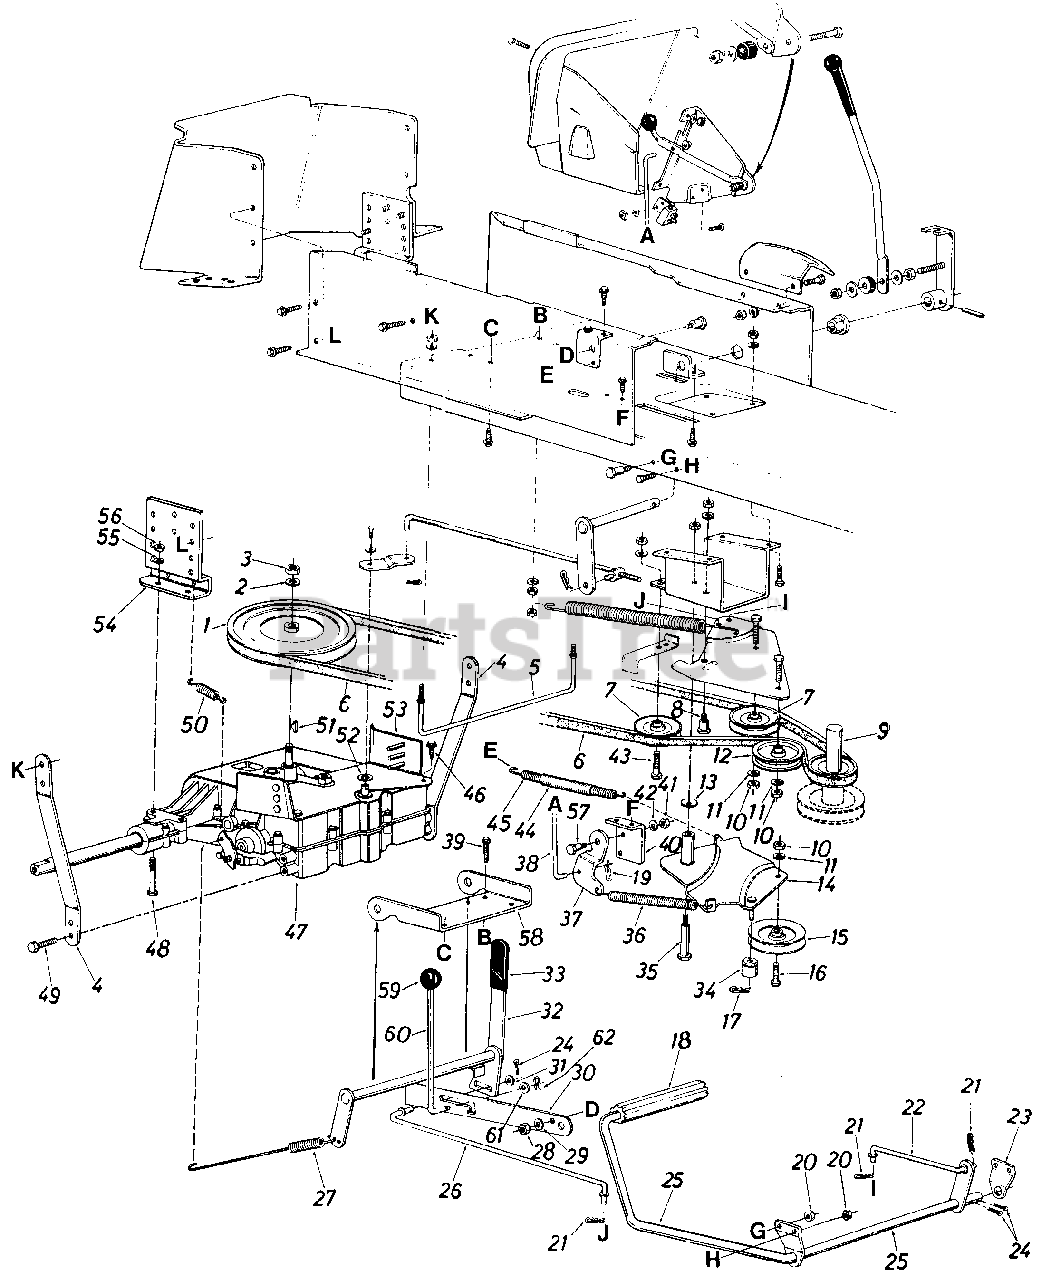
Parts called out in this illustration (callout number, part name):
1	8" "V"-Pulley
2	L-Wash. 1/2" I.D.*
3	Hex Nut 1/2-20 Thd.*
4	Transaxle Brace
6	"V"-Belt
7	"V"-Belt Idler Pulley .38" I.D. x 3-1/16" O.D.
8	Shoulder Bolt .435" Dia. x .160 (5/16-18)
9	Two Step Engine Pulley 3.10" & 5.56" Dia.
10	Hex Nut 3/8-16 Thd.*
11	L-Wash. 318" I.D.*
12	Flat Idler Pulley 2.75" O.D.
13	Belleville Wash. .400'1 I.D. x .88" O.D. x .063
14	Idler Bracket Ass'y.
15	4" "V"-ldler Pulley
16	Hex Bolt 3/8-16 x 1.25" Lg.*
17	Hairpin Cotter 5116" Dia.
18	Foot Pad
19	Intern. Cotter Pin 5116" Dia.
20	Hex Cent. L-Nut 3/8-16 Thd.*
21	Hairpin Cotter 3132" Dia. x 3/4" Lg
22	Brake Clutch Rod (4.60" Lg.)
23	Clutch Rod Bearing Brkt.
24	Cotter Pin 1/8" Dia. x 1.00"
25	Clutch Brake Pedal Ass'y.
26	Brake Cam Rod (13.60" Lg.)
27	Extension Spring .59" O.D. x.93" Lg.
28	Hex Nut 5/16-18 Thd.*
29	L-Wash. 5/16" I.D.*
30	Parking Brake Cam
31	Fl-Wash. .406" I.D. x 1.00" O.D. x .030 Thk.
32	Hand Brake Lever Ass'y.
33	Grip Flat Bar 1-1/4" Wide
34	Spacer
35	Shoulder Bolt .496" Dia. x 2.00" Lg. (3/8-16)
36	Extension Spring .75" O.D. x 6.12" Lg.
37	Deck Control Brkt.
38	Deck Control Rod
39	Hex Wash. Hd. TT-Tap Scr. 1/4-20 x 1.50" Lg
40	Parking Brake Cam Mtg. Brkt.
41	Hex Nut 5/16-18 Thd.
42	L-Wash. 5/16" I.D.
43	Hex Bolt 3/8-24 x 1.50" Lg. (Grade 5)
44	Convoluted Conduit .50" I.D. x 4.0" Lg.
45	Ext. Spring .50" O.D. x 6.37" Lg.
46	Hex Wash. Hd. AB 0 Tap Scr. 5/16-24 x .75" Lg.
47	Transaxle
48	Hex Bolt 5/16-18 x 2.50" Lg.
49	Hex Wash. Hd. AB 0 Tap Scr. 5/16-24 x .75" Lg.
50	Extension Spring .50" O.D. x 2.75" Lg.
51	Hi-Pro Key 3/32" x 5/8" Dia.
52	Special Wash. 1.00" O.D. (Hdn.)
53	Transaxle Belt Keeper Ass'y.
54	Transaxle Support Bracket
55	L-Wash. 5/16" I.D.
56	Hex Nut 5/16-18 Thd.
57	Shoulder Bolt .437" Dia. x .162" Lg. (5/16-18)
58	Idler Mtg. Brkt.
60	Parking Brake Link
61	Fl-Wash.
62	Hairpin Cotter
